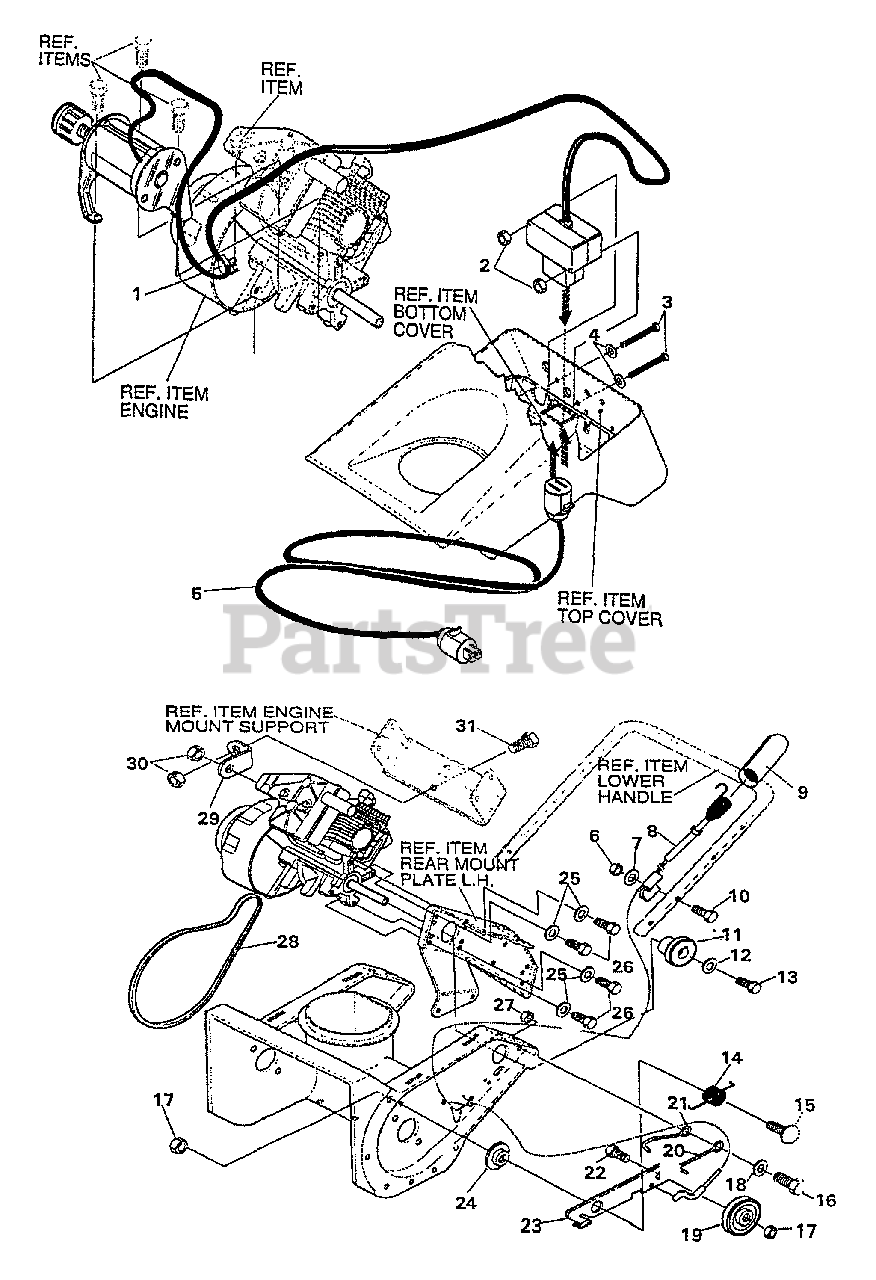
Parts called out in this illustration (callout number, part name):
1	RETAINER, WIRE
2	NUT - 8-32 -- KEPS
3	SCREW - 8-32 X 3"
4	WASHER - .188 X .38 X .040"
5	CORD, EXTENSION 10 FEET
6	NUT - 1/4-20
7	WASHER
8	CABLE, DRIVE CONTROL
9	COVER, CABLE HOLDER
10	SCREW - 1/4-20 X 1-1/2"
11	PULLEY HALF, 3L, 2.00
12	WASHER
13	SCREW - 5/16-24 X 7/8"
14	SPRING, BRAKE
15	BOLT, IDLER ARM
16	SCREW - 3/8-16 X 1"
17	LOCKNUT - 3/8-16
18	WASHER
19	IDLER PULLEY, 1.88X.5X.38
20	GUIDE, BELT .381DX3.30 OFF
21	GUIDE, BELT .381DX2.66
22	BOLT - 3/8-16 X 1.25"
23	BRACKET, IDLER ARM
24	SPACER
25	LOCKWASHER
26	SCREW - 5/16-18 X 3/4"
27	NUT - 3/8-16
28	BELT, V3LX35, .048 D
29	SUPPORT, ENGINE
30	NUT - 5/16-18
31	SCREW - 5/16-18 X 1/2"
